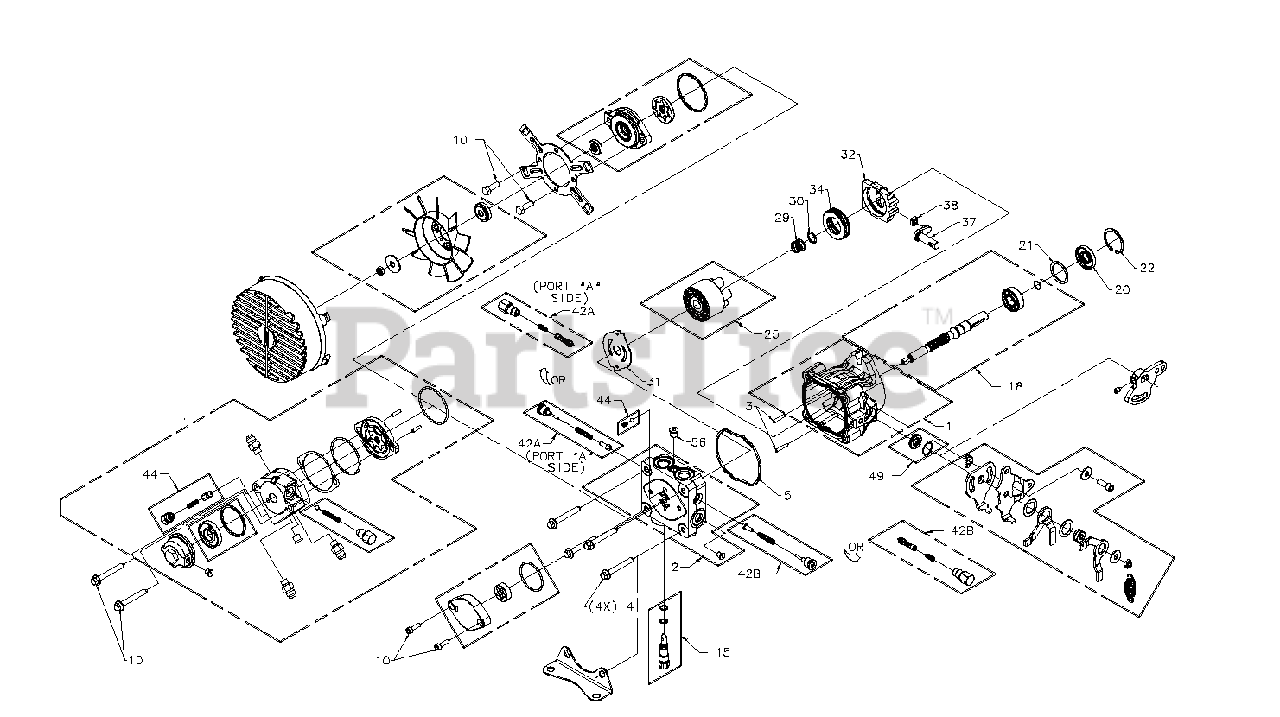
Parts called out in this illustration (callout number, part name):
1	Kit, Housing
2	Kit, End Cap W/PPT & STD
3	Pin, .219 x 1
4	Hex, Flange Bolt M8-1.25 x 60mm
5	Kit, Chg Pump
10	Screw, Cap M6 x 1 x 25
15	Kit, Bypass Valve
18	Kit, Pump Shaft 15mm Keyw
20	Seal, Lip 17 x 40 x 7
21	Washer 1.23 x 1.56 x .04
22	Ring, Ret 1.56 Int
25	Kit, 10 CC Block
29	Spring, Block
30	Washer, Thrust .59 x .78 x .04
31	Plate, Valve
32	Swashplate 10cc
34	Bearing, Thrust Ball 30 x 52 x 13
37	Arm, Trunnion 10 Cc
38	Guide, Slot
42	Kit, Shock Valve 200 Bar
44	Kit, Chg Relief
49	Kit, BDP-10l Seal
56	Plug 7/16-20 (Metal)
NS	Kit, Overhaul Seal
